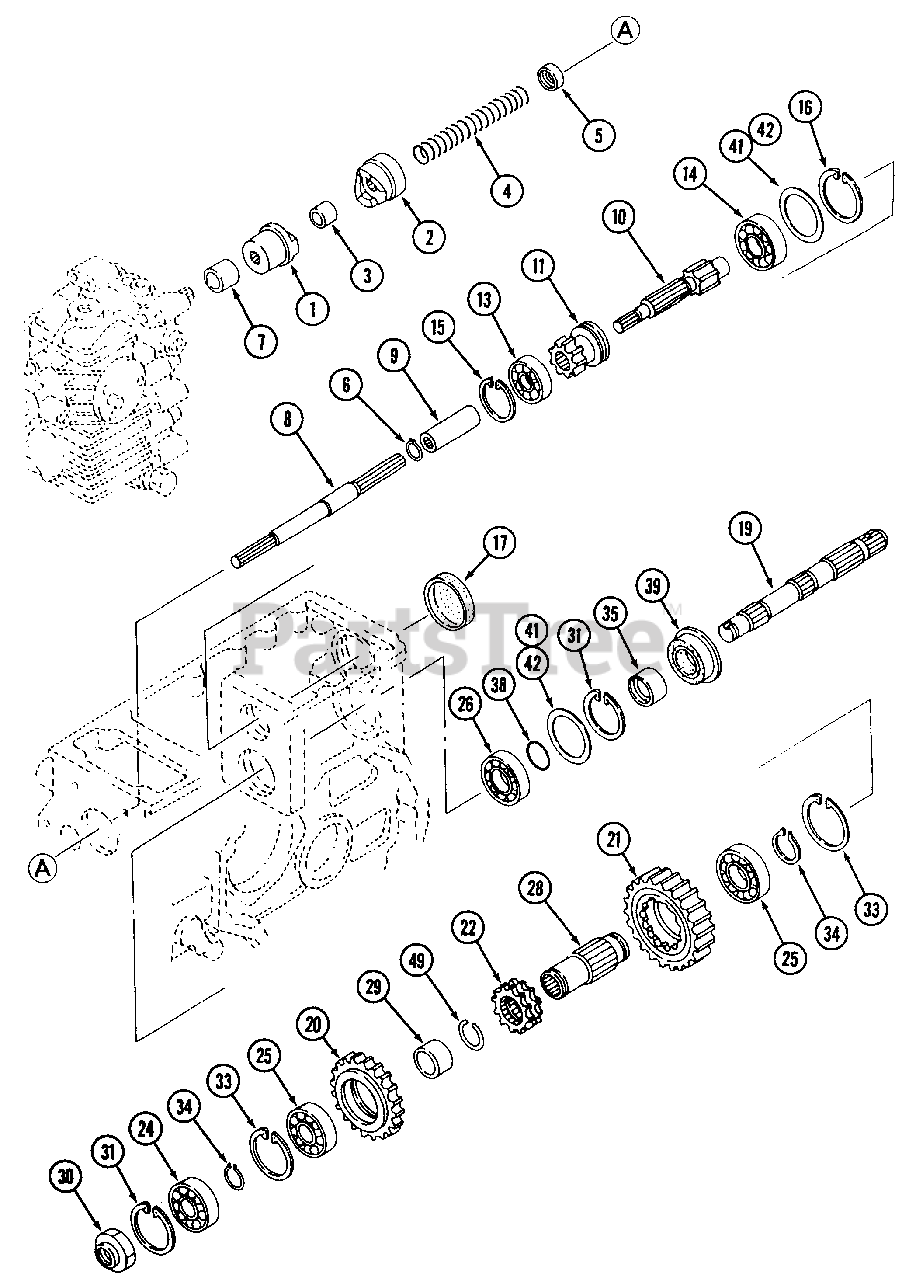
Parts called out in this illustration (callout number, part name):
6	Ring
9	Joint
10	Shaft PTO Drive
34	Ring
39	Seal, Oil
